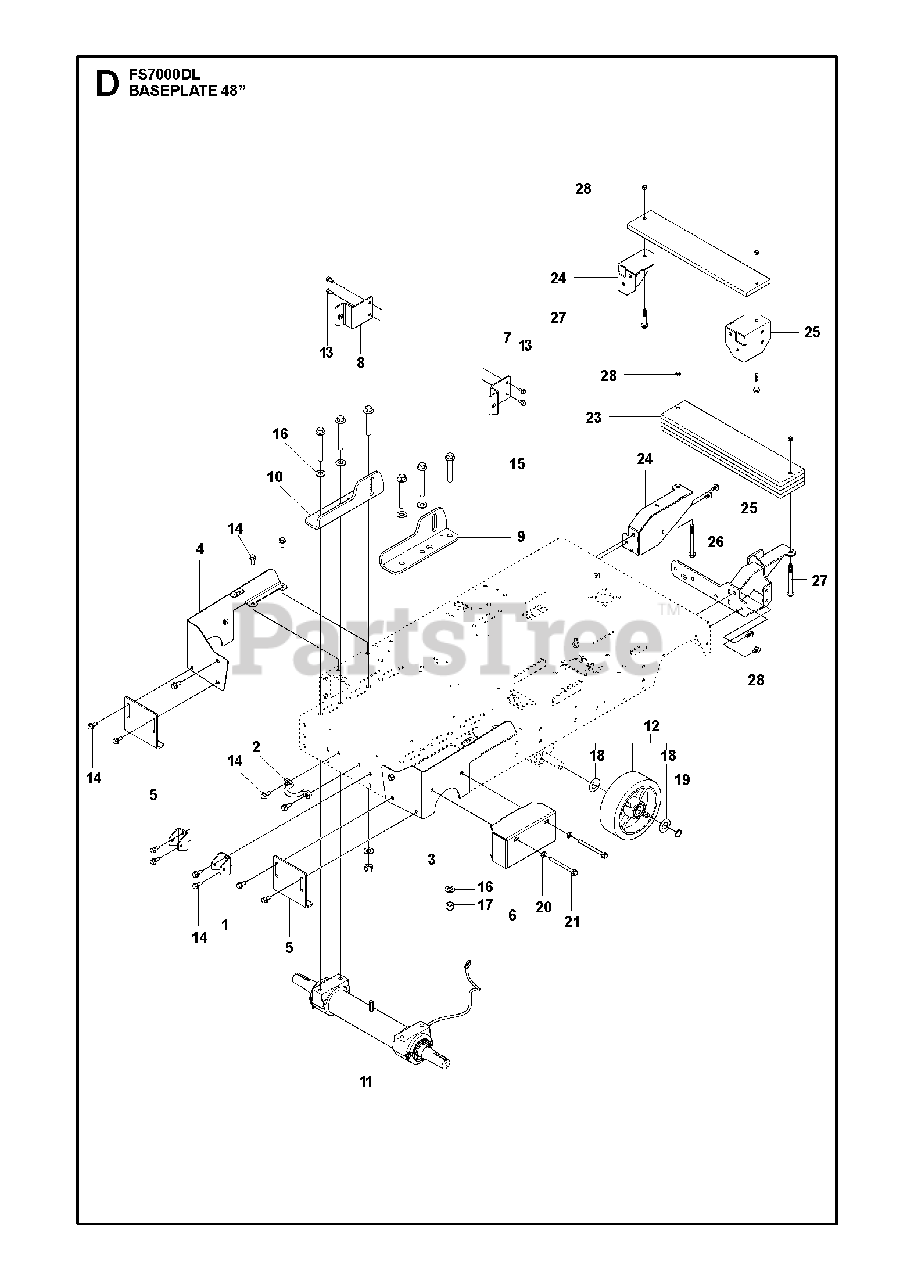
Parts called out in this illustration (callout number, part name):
19	CIRCLIP
20	WASHER
23	WEIGHT1 speed or 3-speed w/ 5th Wheel
23	WEIGHT3-speed w/o 5th Wheel
27	SCREW EHHFMwith 1 Weight
27	SCREW EHHFMwith 4 Weights
